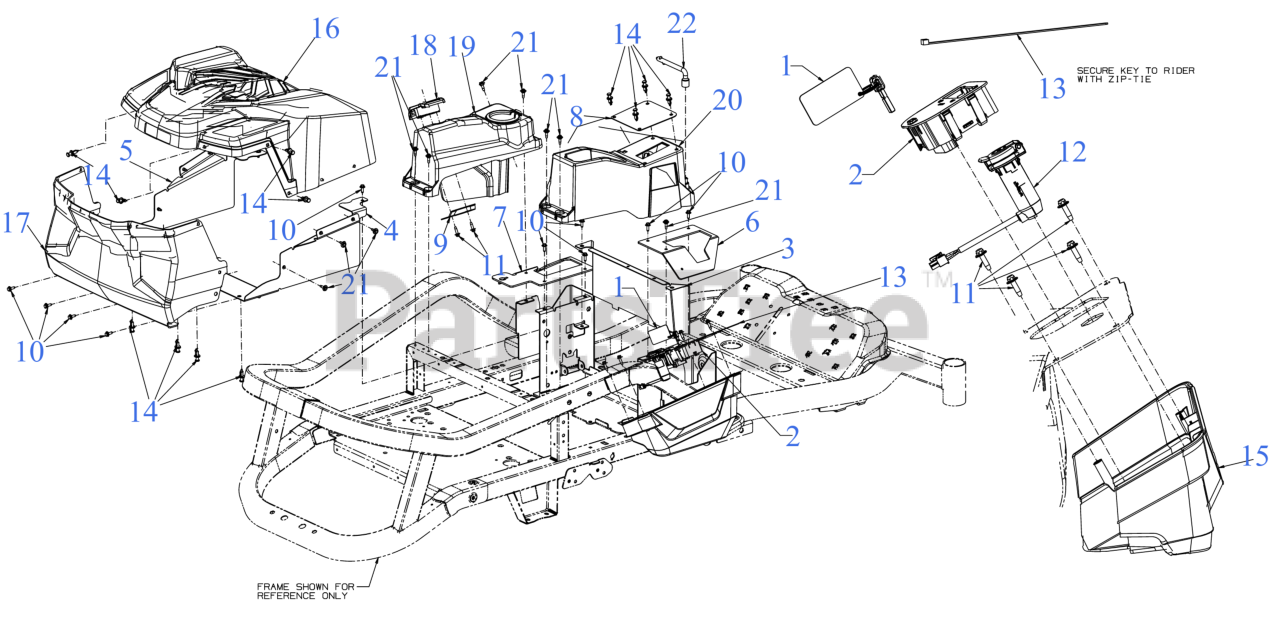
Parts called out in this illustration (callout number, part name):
1	MAGNETIC KEY
2	VCM SWITCH ASSEMBLY
3	SEAT BOX FRONT PLATE
4	BATTERY MOUNT BRACKET (RH)
5	BATTERY MOUNT BRACKET (LH)
6	CONTROL BRACKET (RH)
7	CONTROL BRACKET (LH)
8	CONSOLE COVER PLATE
9	CHARGER ADAPTER PLATE
10	SCREW M6-1 x .625
11	SCREW 1/4-10 x .750
12	USB RECEPTACLE (12V W/JUMPER)
13	TIE CABLE 8.5 LG
14	PLASTIC RIVET
15	CONTROL PANEL CONSOLE
16	BATTERY COVER
17	BATTERY COVER (REAR)
18	CHARGER ADAPTER
19	CONSOLE (LH)
20	BATTERY CONSOLE (RH)
21	SHOULDER SCREW M6-1 .368 X.115
22	MULTI TOOL 1/2" SOCKET
